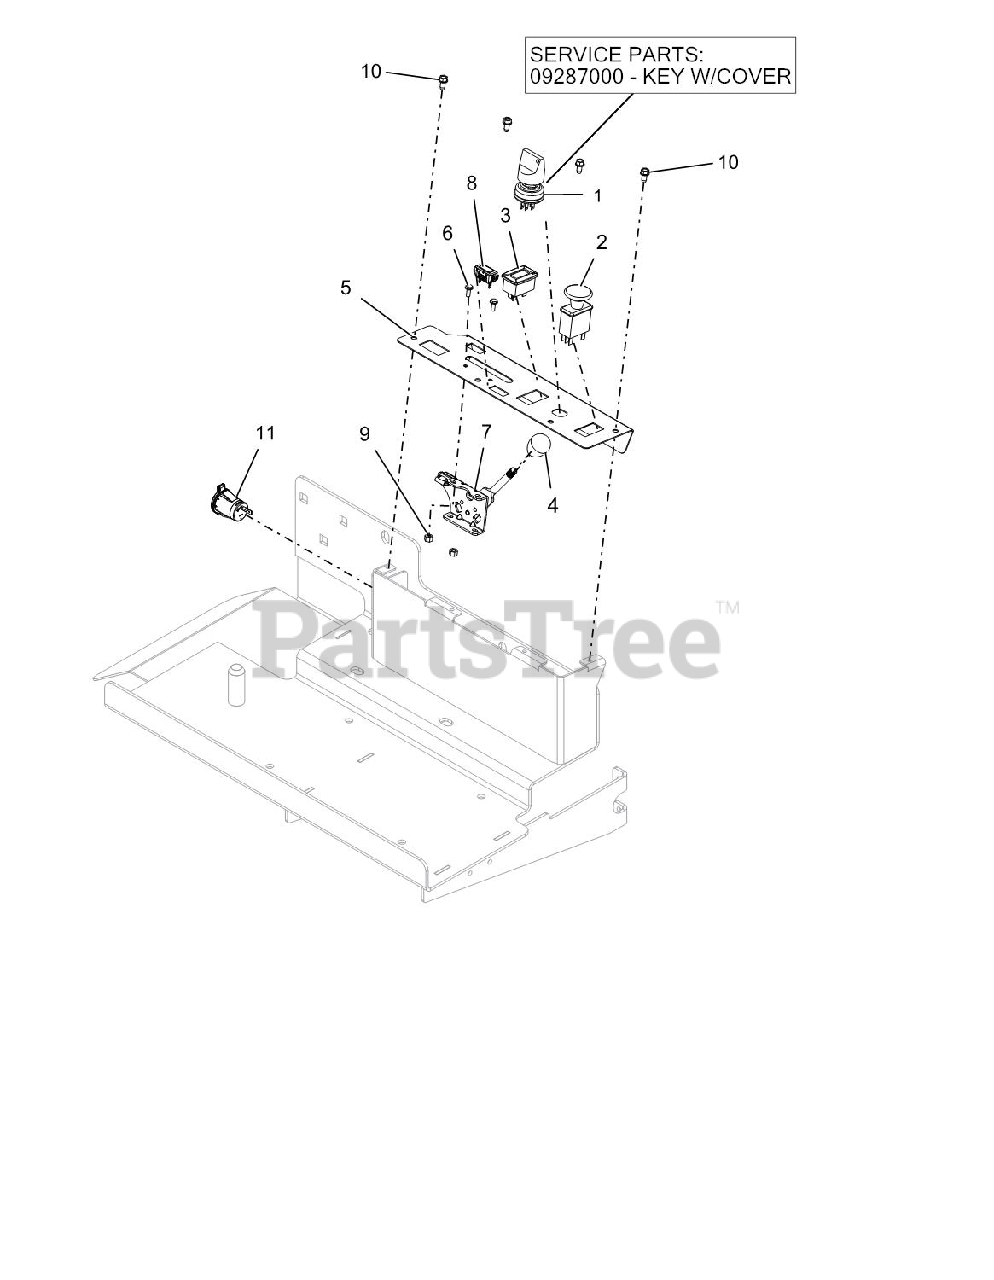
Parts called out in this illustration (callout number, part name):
1	KEY, W/ SHIELD
1	SWITCH, IGNITION
2	SWITCH, CLUTCH
3	METER, HOUR W/MAINTENANCE
4	KNOB-CONTROL-BLACK .38-16X.50
5	PANEL, CONTROL-PT400 LP
6	SCR-MCH 10-24X.50 HWH YWZC
7	CABLE, PT100 THROTTLE CONTROL
8	LIGHT,INDICATOR
9	NUT-LK-NYL 10-24 W/INSRT YWZC
10	SCR-TAP .25-20X.50 HWH TR YWZ
11	PORT, 12 VOLT POWER
